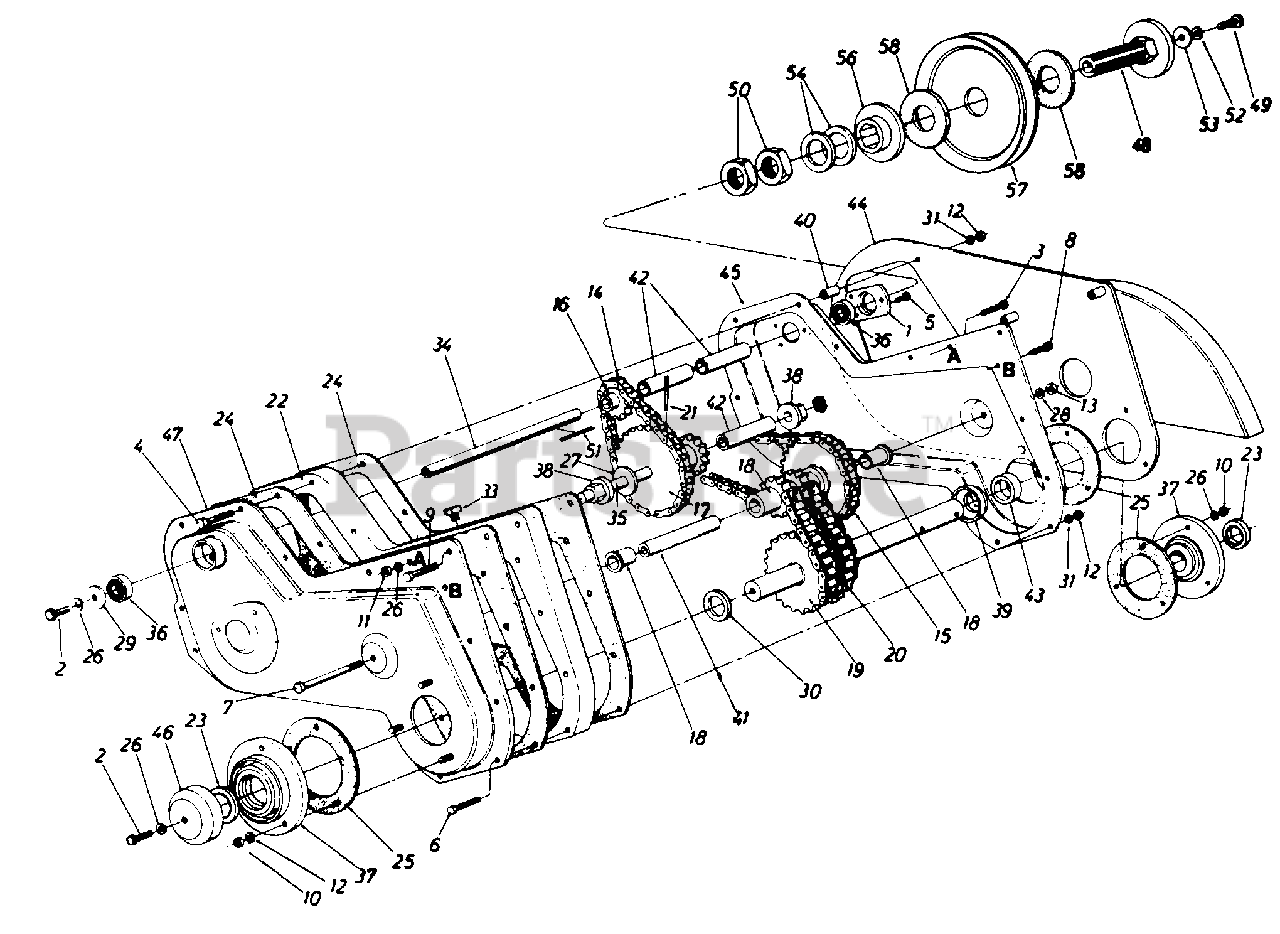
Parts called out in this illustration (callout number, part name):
1	Bearing Housing 1-3/8" Dia.
2	Hex Bolt 5/16-18 x .88"
3	Hex Bolt 5/16-18 x 1.5" Lg.
4	Hex Bolt 1/4-20 x 2.75" Lg.
5	Hex S-Tap Scr. 1/4-20 x .5" Lg.
6	Hex Bolt 1/4-20 x 1.5" Lg.
7	Hex Bolt 3/8-16 x 4.5" Lg.
8	Hex Scr. 1/4-20 x 1.5" Lg.
9	Hex TT-Tap Scr. 5/16-18 x 1.75"
10	Hex L-Nut 5/16-18 Thd.
11	Hex Nut 5/16-18 Thd.
12	Hex Nut 1/4-20 Thd.
13	Hex Nut 3/8-16 Thd.
14	#41 Chain1/2" Pitch x 34 Links Endless
15	#42 Chain1/2" Pitch x 48 Links Endless
16	Sprocket 10 Tooth .5" Pitch
17	10 & 28 Teeth Sprocket Ass'y.
18	8-2 & 28 Sprocket Sleeve Ass'y.
19	18-2 Sprocket Shaft Ass'y.
20	#50-2 Chain 5/8" Pitch x 28 Links Endless
21	Spring Pin Spir. 1/4 Dia x 1.5" Lg.
22	Spacer Block Tiller Housing
23	Oil Seal 1-1/4" Dia.
24	Gasket for Tiller Housing
25	Gasket for Brg. Housing
26	L-Wash. 5/16" I.D.
27	Fl-Wash. .64" I.D. x 1.24" O.D.
28	L-Wash. 3/8" 1 .D. H.D.
29	Fl-Wash. .344" I.D. x 1.125"
30	Special Washer
31	L-Wash. 1/4" I.D.
33	Vent Plug
34	Jack Shaft .525" I.D. x 7.78"
35	Sprocket Shaft .63" Dia. x 5"
36	Ball Brg. .62" I.D. x 1.38" O.D.
37	Bearing Housing 1-1/4"
38	Hex Flange Brg.
39	Spacer 1.25" I.D. x 2.0" O.D.
40	Spacer .9" Lg.
41	Spacer 3.44" Lg.
42	Spacer 1.56" Lg.
43	Spacer .5" Lg.
46	Dust Cap
49	Hex Bolt 5/16-18 x 1.25" Lg. Grade 5
50	Hex Jam Nut 1.0-14 x 28 Thd.
51	Sq. Key 3/16 x 1.5" Lg.
52	L-Wash. 5/16" I.D.
53	Fl-Wash. .344" I.D. x 1.125"
54	Bell-Wash. 1.0" I.D. x 2.0"
56	Floating Disc 3-1/4" O.D.
57	5/8 V-Pulley 1.5" I.D. x 6.5"
58	Friction Pad 3-1/4" O.D. x 1-3/8" I.D.
